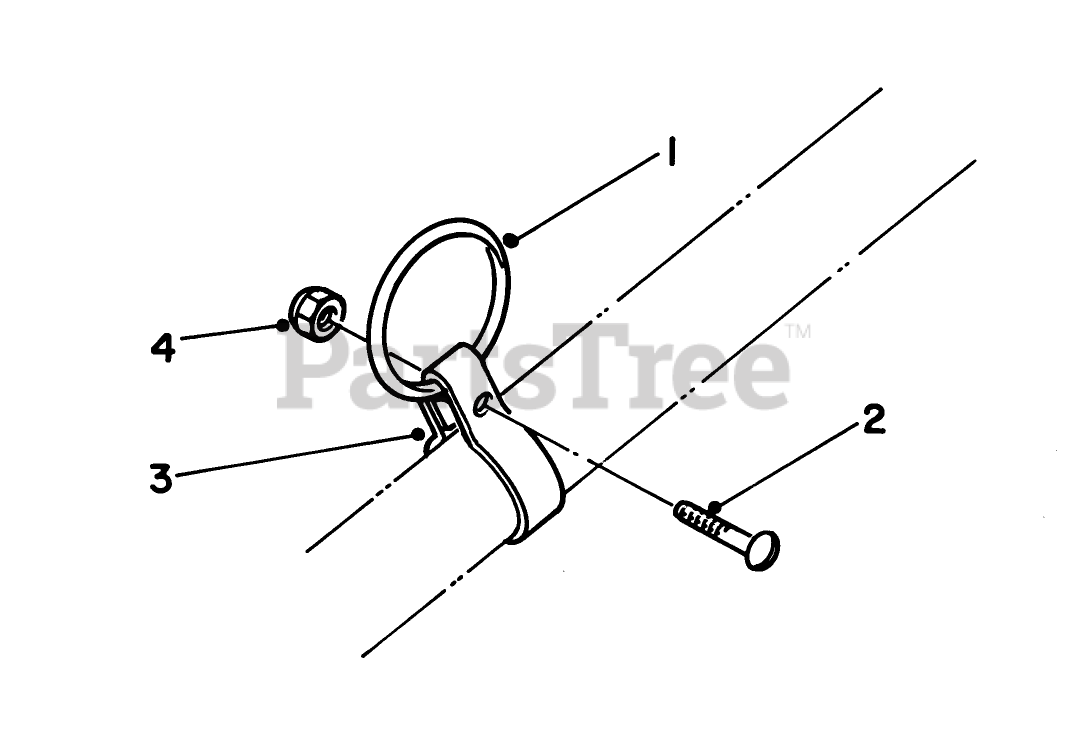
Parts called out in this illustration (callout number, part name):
1	Ring
2	10-24 X 5/8 PAN HD MS
3	Clamp
4	NUT-LOCK, NI
